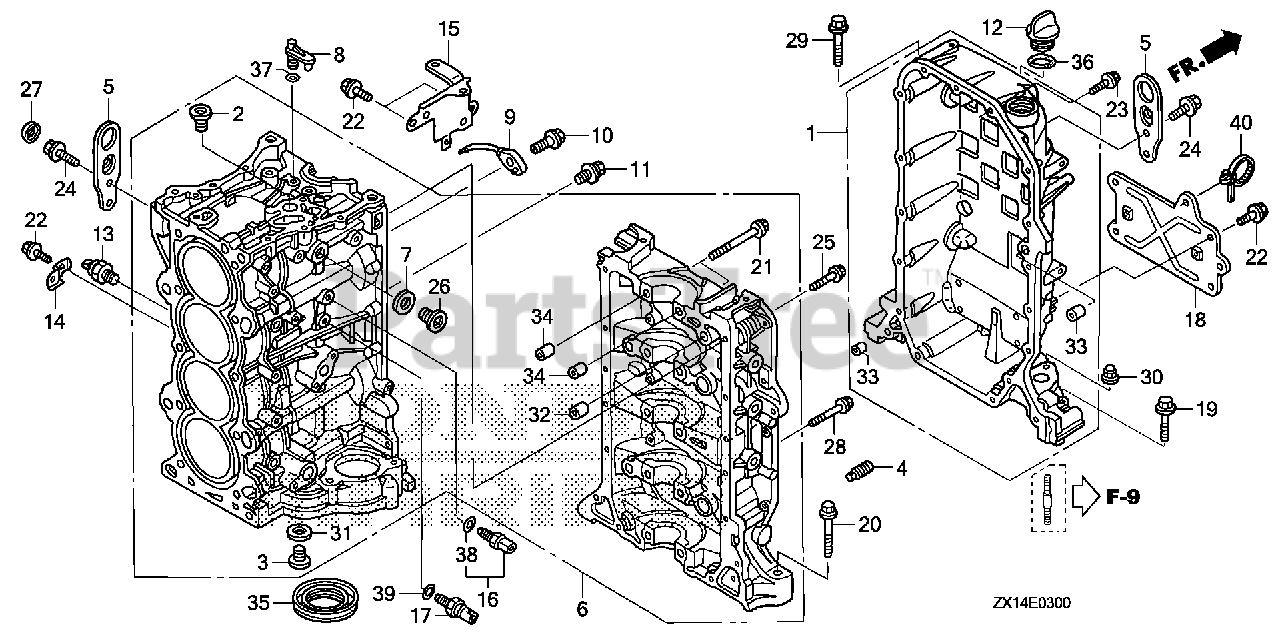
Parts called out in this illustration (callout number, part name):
1	CRANKCASE
2	BOLT, SEALING (20MM)
3	BOLT, SEALING (28MM)
4	ORIFICE, BLOCK (LOWER)
5	HANGER, ENGINE
6	BLOCK ASSY., CYLINDER *NH8* (DARK GRAY)
6	BLOCK ASSY. *NH8*
7	WASHER, SEALING (22MM)
8	ORIFICE, OIL JET
9	BODY, OIL JET
10	BOLT, OIL JET
11	BOLT-WASHER (8X10)
12	CAP, OIL
13	SENSOR ASSY., KNOCK
14	BRACKET, CLIP B
15	BRACKET D, HARNESS CLIP
16	SENSOR ASSY., WATER TEMPERATURE
17	SENSOR, OIL PRESSURE
18	BRACKET, RELAY
19	BOLT, FLANGE (8X55)
20	BOLT, FLANGE (12X83)
21	BOLT-WASHER (11X95)
22	BOLT, FLANGE (6X14) (CT200)
23	BOLT, FLANGE (6X25)
24	BOLT, FLANGE (8X20)
25	BOLT, FLANGE (8X35)
26	BOLT, SEALING (22MM)
27	CAP, BOLT (8MM)
28	BOLT, FLANGE (8X50)
29	BOLT, FLANGE (10X70)
30	NUT, FLANGE CAP (10MM)
31	WASHER, SEALING (28MM)
32	PIN, DOWEL (18X22)
33	PIN, DOWEL (13X20)
34	PIN, DOWEL (13X14)
35	OIL SEAL (80X98X10)
35	OIL SEAL (80X98X10) (ARAI)
36	O-RING (26X2.7)
37	O-RING (6.5X1.5)
38	O-RING (9.5X1.9)
39	O-RING (13X1.5) (ARAI)
40	CLIP, HARNESS BAND (145MM) (BLACK)
